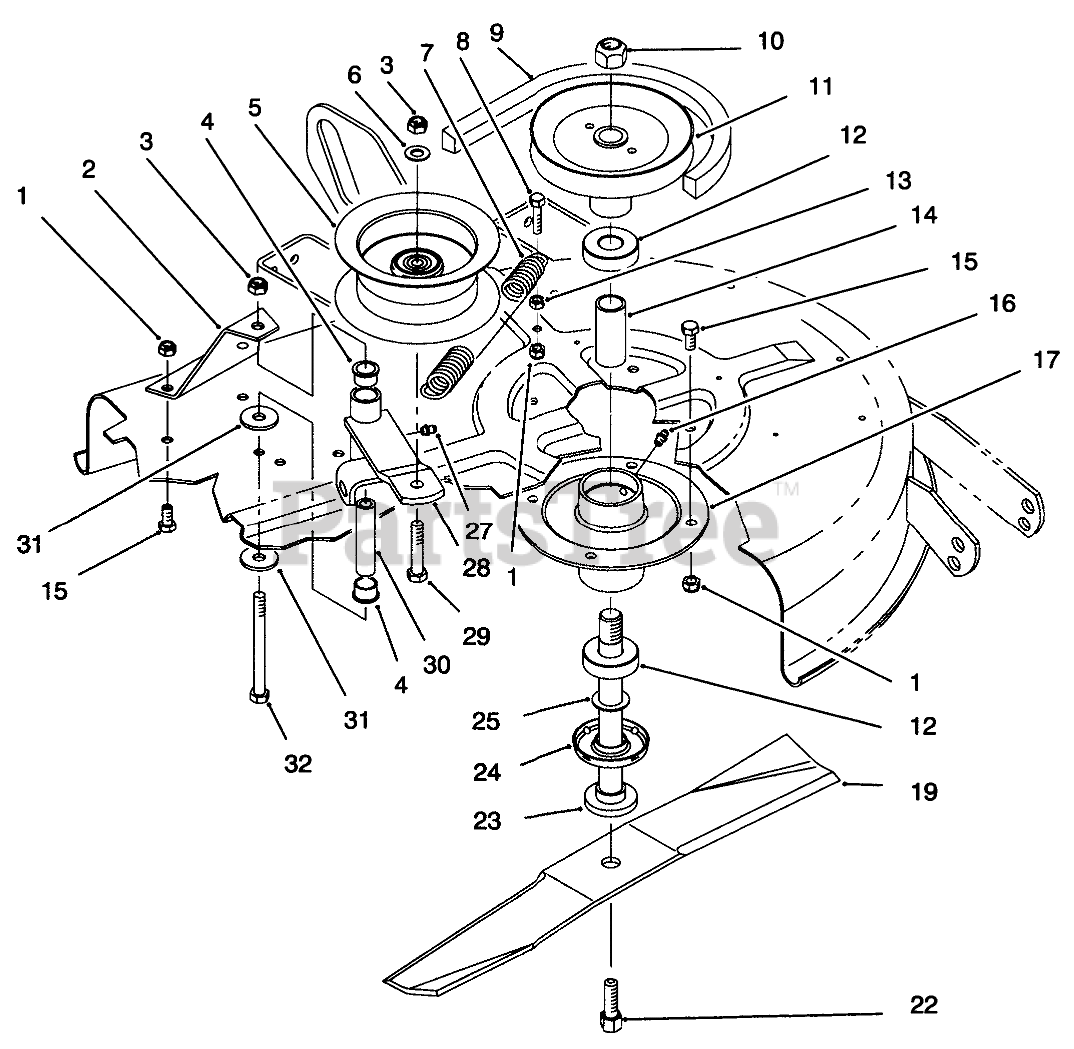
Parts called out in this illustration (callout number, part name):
1	NUT-LOCK, NI
3	NUT-LOCK, NI
4	BUSHING
5	PULLEY-IDLER
6	WASHER-FLAT
7	SPRING-EXTENSION
8	SCREW-HH
9	V-BELT
10	Nut-Hex
11	PULLEY
12	BEARING-BALL
13	NUT-HEX
14	SPACER
15	SCREW-HH
16	ZERK FITTING
17	HOUSING-SPINDLE (BLACK)
19	Blade
21	WASHER
22	SCREW-HH
23	SHAFT-SPINDLE
24	SHIELD-BEARING
25	SPACER-HARDNED
27	FITTING-GREASE
28	WLDMT-IDLER ARM (BLACK)
29	SCREW-HH
30	SPACER
31	WASHER
32	SCREW-HH
